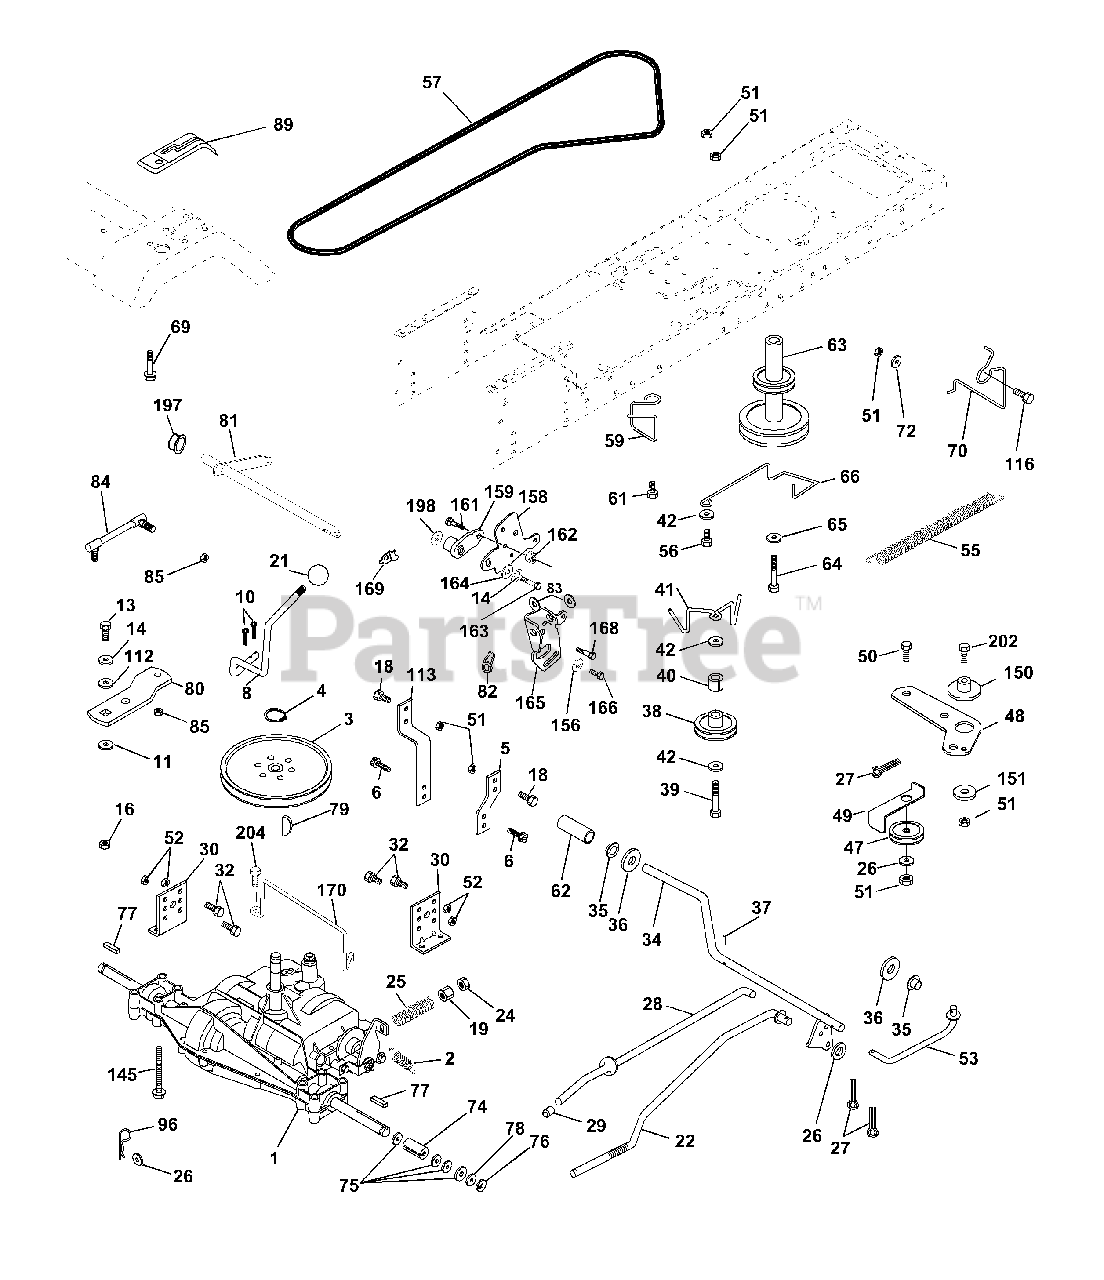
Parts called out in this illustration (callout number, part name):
2	Spring Return Brake T/a Zinc
3	Pulley Transaxle 18" tires
4	Ring Retainer # 5100-62
5	Strap Torque 30 Degrees
6	Screw 5/16-18 X 3/4
8	Rod Shift Fender Adjust Lt
10	Pin Cotter 1/8 X 1 Cad
11	Washer Plate Shf 388 Sq Hole
13	Bolt 1/4-28 Unf Gr 8 W/Patch
14	Washer Lock Hvy Helical
16	Nut Lock Hex w/ins 5/16-18
18	Bolt, Fin Hex 3/8-16 UNC x 1 Gr. 5
19	Nut Lock 3/8-16 Unc
21	Knob
22	Rod Brake Blk Zinc 26 840
24	Nut Hex Jam 3/8-16 Unc
25	Spring Rod Brake 2 00 Zinc
26	Washer 13/32 X 13/16 X 16 Ga
27	Pin Cotter 1/8 X 3/4 Cad
28	Rod Brake Parking LT/YT
29	Cap Brake Parking
30	Bracket Mtg Transaxle
32	Bolt Hex Hd 5/16-18unc X 3/4
34	Shaft Asm Pedal Foot
35	Bearing Nylon Blk 629 Id
36	Washer 21/32 X 1 X 16 Ga
37	Pin Roll 3/16 X 1"
38	Pulley Idler Flat
39	Bolt Fin Hex 3/8-16 unc X 2-3/4
40	Spacer Split 395 X 59 Bzp
41	Keeper Belt Flat Idler
42	Washer 13/32 X 13/16 X 12 Ga
47	Pulley Idler V Groove Plastic
48	Bellcrank Asm
49	Retainer Belt Style Spring
50	Bolt Hex Hd 3/8-16unc X 1-1/2
51	Nut Crownlock 3/8-16 Unc
52	Nut Crownlock 5/16-18 Unc
53	Link Clutch
55	Spring Return Clutch 6 75
56	Bolt Fin Hx 3/8-16 X 1/4
57	V-Belt Ground Drive 95 25
59	Keeper Belt Span Ctr
61	Screw 3/8-16x.75
62	Cover Pedal Blk Round
63	Engine Pulley LT/YT
64	Bolt Hex
65	Washer Lock Hvy Hlcl Spr 7/16
66	Keeper Belt Engine Foolproof
69	Screw Hex wsh Hi Lo 1/4 x 1/2 unc
70	Guide Belt Mower Drive RH
72	Washer 13/32 X 1-1/4 X 12 Ga
74	Spacer Axle
75	Washer 25/32 X 1 1/4 X 16 Ga
76	E-ring #5133-75
77	Key Square 2 0 X 1845/ 1865
78	Washer 25/32 X 1-5/8 X 16 Ga
79	Key Woodruff #9 3/16 x 3/4
80	Arm Shift
81	Shaft Asm Cross Tapered PMST/20
82	Spring Torsion T/a
83	Washer 17/32 X 3/4 X 16 Ga
84	Link Transaxle PMST/20" Zinc
85	Nut Lock Center 1/4 - 28 FNTHD
89	Console Shift STLT
96	Retainer Spring 1"
112	Washer 9/32 x 3/4 x 10 Ga.
113	Strap Torque LT
116	Bolt Rdhd Sq Neck 3/8-16 x 1.25
145	Bolt Hex FLGHD 5/16-18 Gr. 5
150	Bushing Bellcrank
151	Washer 13/32 x 2 x 10
156	Washer Srrted 5/16ID x 1.125
158	Bracket Shift Mount
159	Hub Tapered Flange Shift Lt
161	Bolt Rdhd Sqnk 1/4-20 x 3/4 Gr
162	Nut Crownlock 1/4-20 Unc
163	Bolt Hex Fin 1/4-20 Unc x 1 Gr 5
164	Washer 5/8 x .281 x 10 Ga
165	Bracket Pivot Lever
166	Screw 5/16-18 x 5/8
168	Bolt Shoulder 5/16-18 x .561
169	Plate Fastening
170	Keeper Belt Transaxle Gear
197	Nyliner Snap-In
198	Washer Nyliner
202	Bolt Carr Sh 3/8-16 x 1-1/2 Gr. 5
204	Screw 5/16-18 x 1
